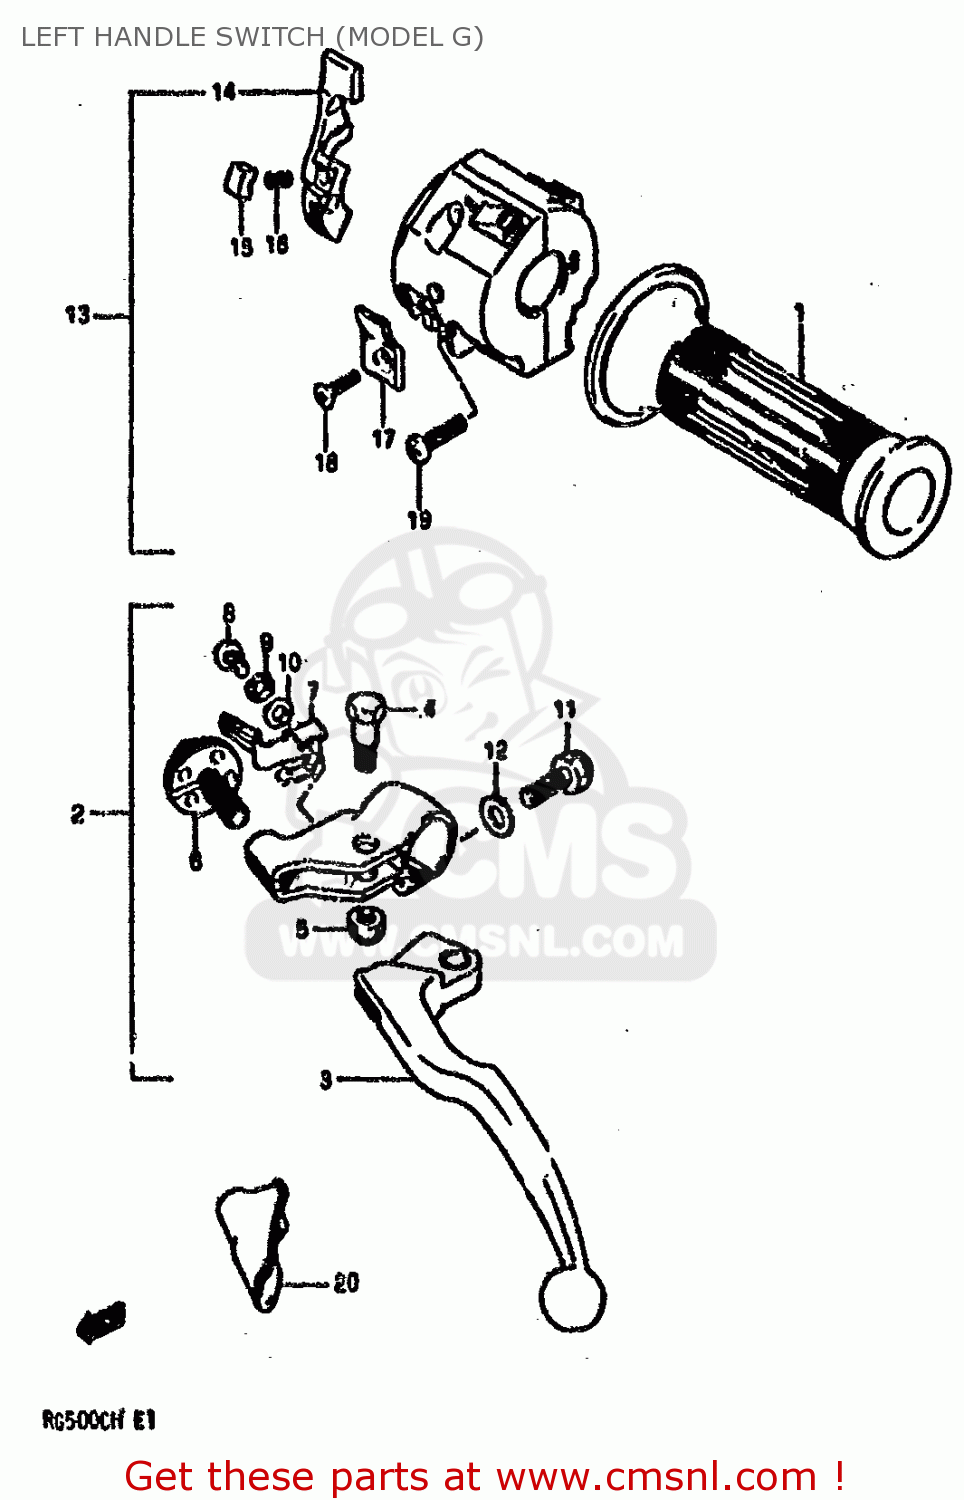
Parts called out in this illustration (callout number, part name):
1	GRIP,L
2	LEVER ASSY,CLUTCH
3	LEVER,CLUTCH
4	BOLT,LEVER PIVOT
5	NUT
6	ADJUSTER,LOCK
7	ADJUSTER,SPRING
8	SCREW
9	LOCK WASHER
10	WASHER
11	BOLT
12	WASHER
13	SWITCH ASSY,HANDLE LH
14	LEVER,CHOKE
15	PIECE,SLIDE
16	SPRING
17	COVER
18	SCREW
19	SCREW 5X20
20	COVER,CLUTCH LEVER
